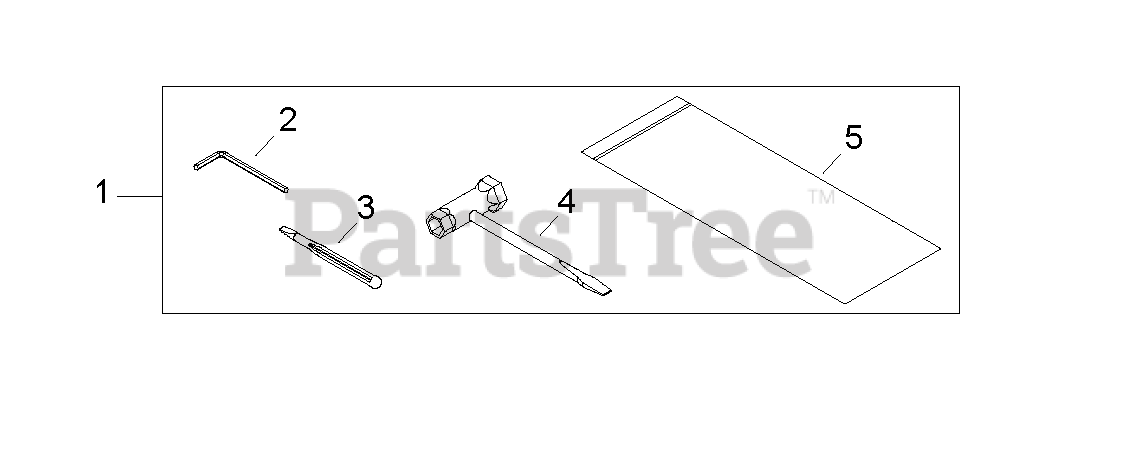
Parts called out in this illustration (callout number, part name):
1	TOOL KIT
2	HEX KEY - 4mm
3	SCREWDRIVER - PLASTIC
4	T-WRENCH - 13X19mm
5	BAG, TOOL
